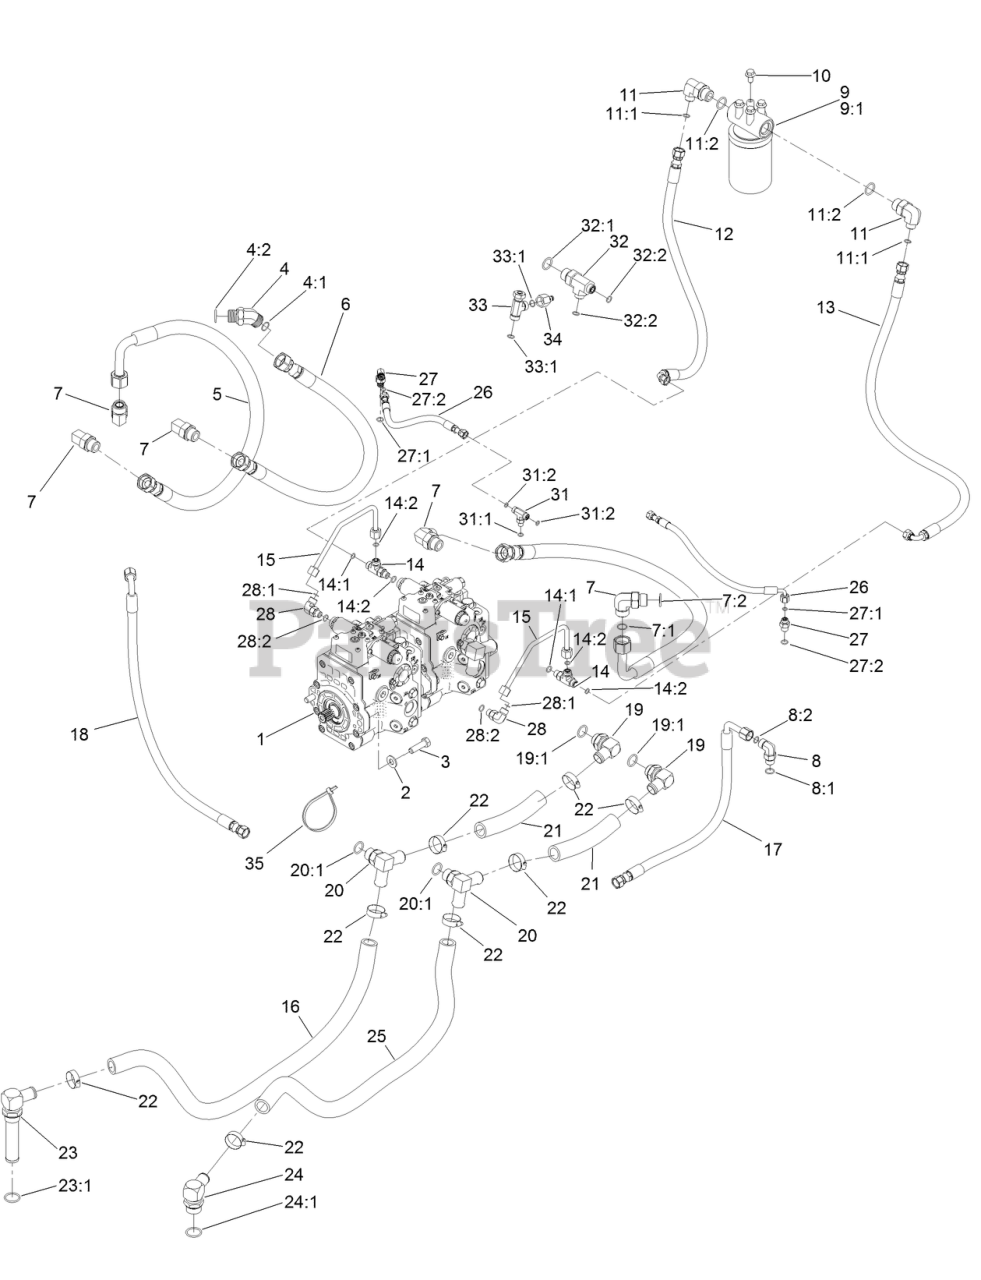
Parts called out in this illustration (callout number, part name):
1	HYD PUMP ASM
2	WASHER-THRUST
3	SCREW-HH
4	FITTING-45 DEG
4:1	O-RING
4:2	O-RING
5	HYD HOSE ASM
6	HYD HOSE ASM
7	FITTING-ELBOW-90
7:1	O-RING
7:2	O-RING
8	FITTING-ELBOW, 90 DEG
8:1	O-RING
8:2	O-RING
9	FILTER-OIL
9:1	FILTER-HYD
10	SCREW-HHF
11	FITTING-HYD, 90 DEG
11:1	O-RING
11:2	O-RING
12	HYD HOSE ASM
13	HYD HOSE ASM
14	FITTING-TEE
14:1	O-RING
14:2	O-RING
15	HYD TUBE ASM
17	HYD HOSE ASM
18	HYD HOSE ASM
19	FITTING-90
19:1	O-RING
20	CONNECTOR
20:1	O-RING
22	CLAMP-HOSE
23	STRAINER FITTING ASM
23:1	O-RING
24	STEM-BARB-90
24:1	O-RING
26	HYD HOSE ASM
27	FITTING-ELBOW, 90 DEG
27:1	O-RING
27:2	O-RING
28	FITTING-ELBOW, 90 DEG
28:1	O-RING
28:2	O-RING
31	FITTING-TEE
31:1	O-RING
31:2	O-RING
32	FITTING-TEE
32:1	O-RING
32:2	O-RING
33	FITTING-HYD, TEE
33:1	O-RING
34	FITTING
35	TIE-CABLE
